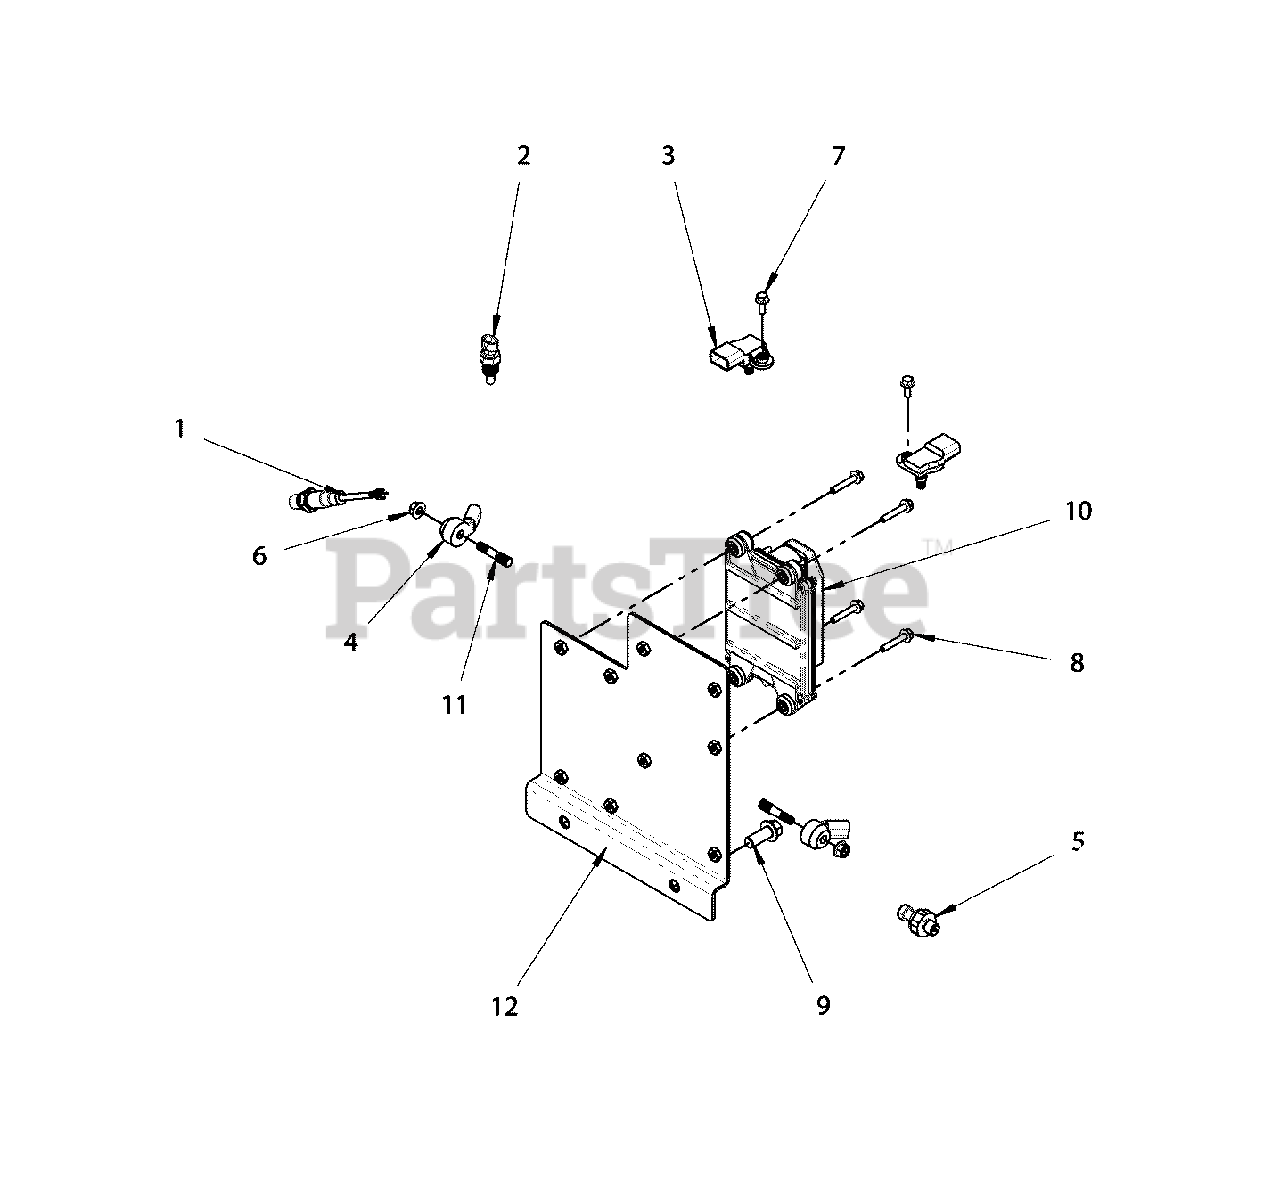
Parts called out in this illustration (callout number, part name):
1	O2 SENSOR
2	COOLANT SENSOR
3	T MAP SENSOR
4	KNOCK SENSOR
5	PRESSURE SENSOR
6	* NUT
7	* BOLT
8	* BOLT
9	* BOLT
10	PROGRAMMED ECU STANDBY
10	* PROGRAMMED ECU PRIME
11	* STUD
12	* BRACKET
